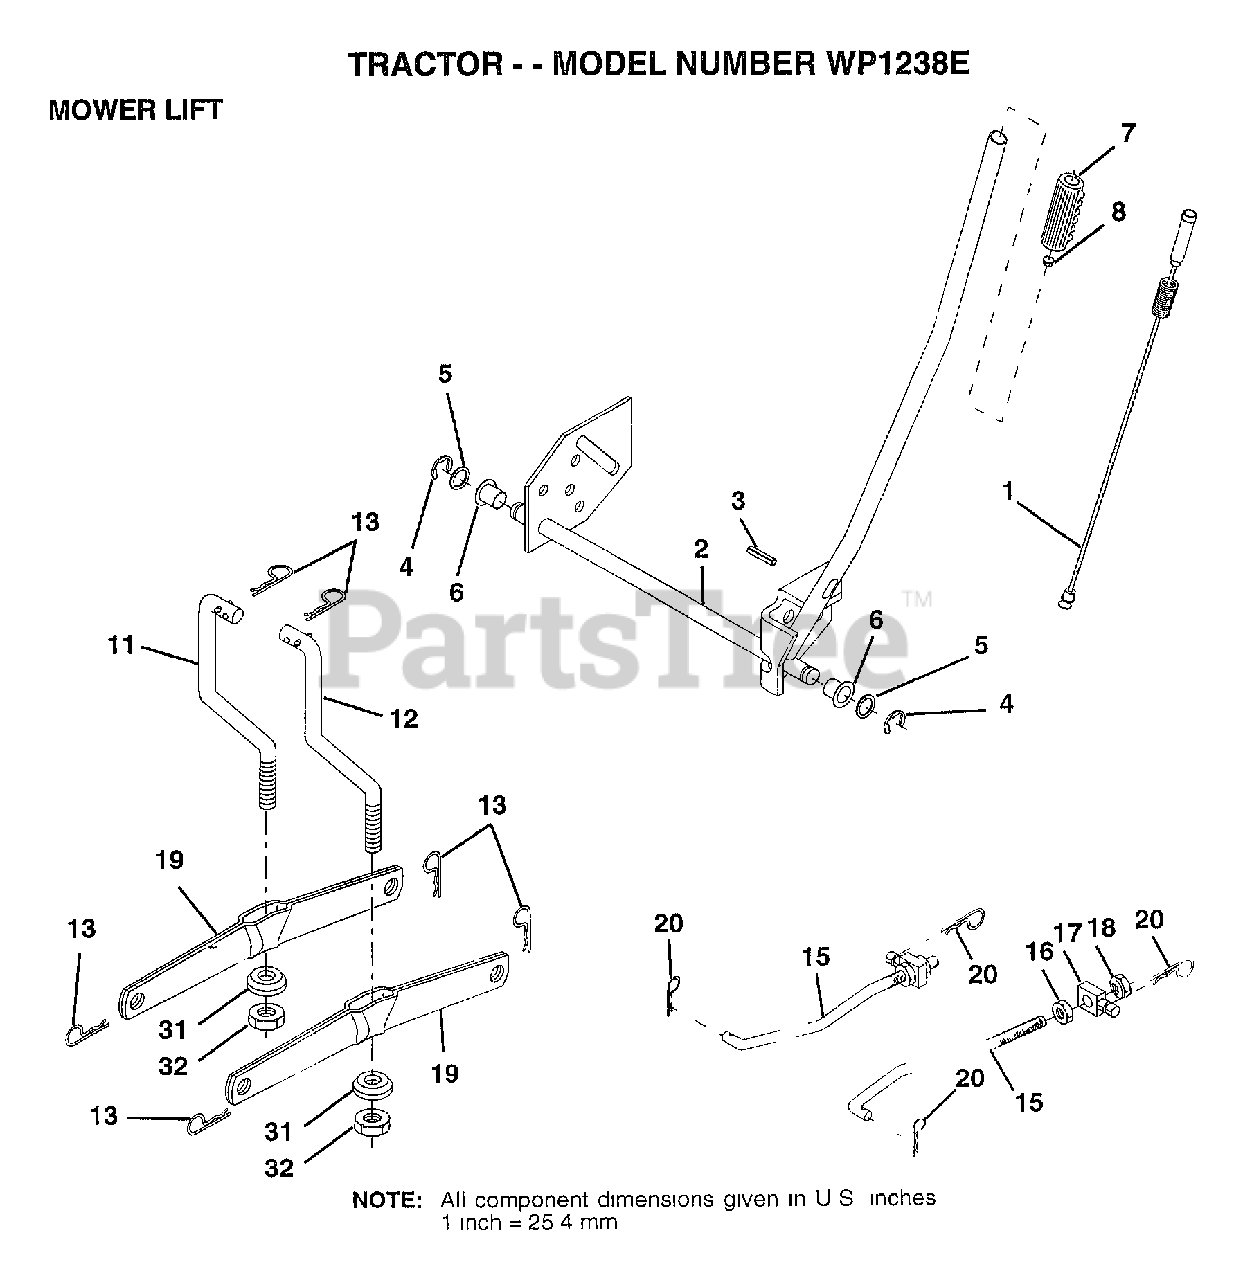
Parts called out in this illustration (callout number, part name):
1	WIRE ASM W.SPRING
2	SHAFT ASM.LIFT
3	PIN-GROOVE LT
5	WASHER
6	NYLON BEARING
7	GRIP
15	LINK.FRONT
16	NUT
17	TRUNION
18	NUT.LK.W/WSH.1/2.
19	ARM SUSP REAR
20	RETAINER SPRING
31	BEARING PVT LH
32	NUT.CROWNLOCK.3/8
